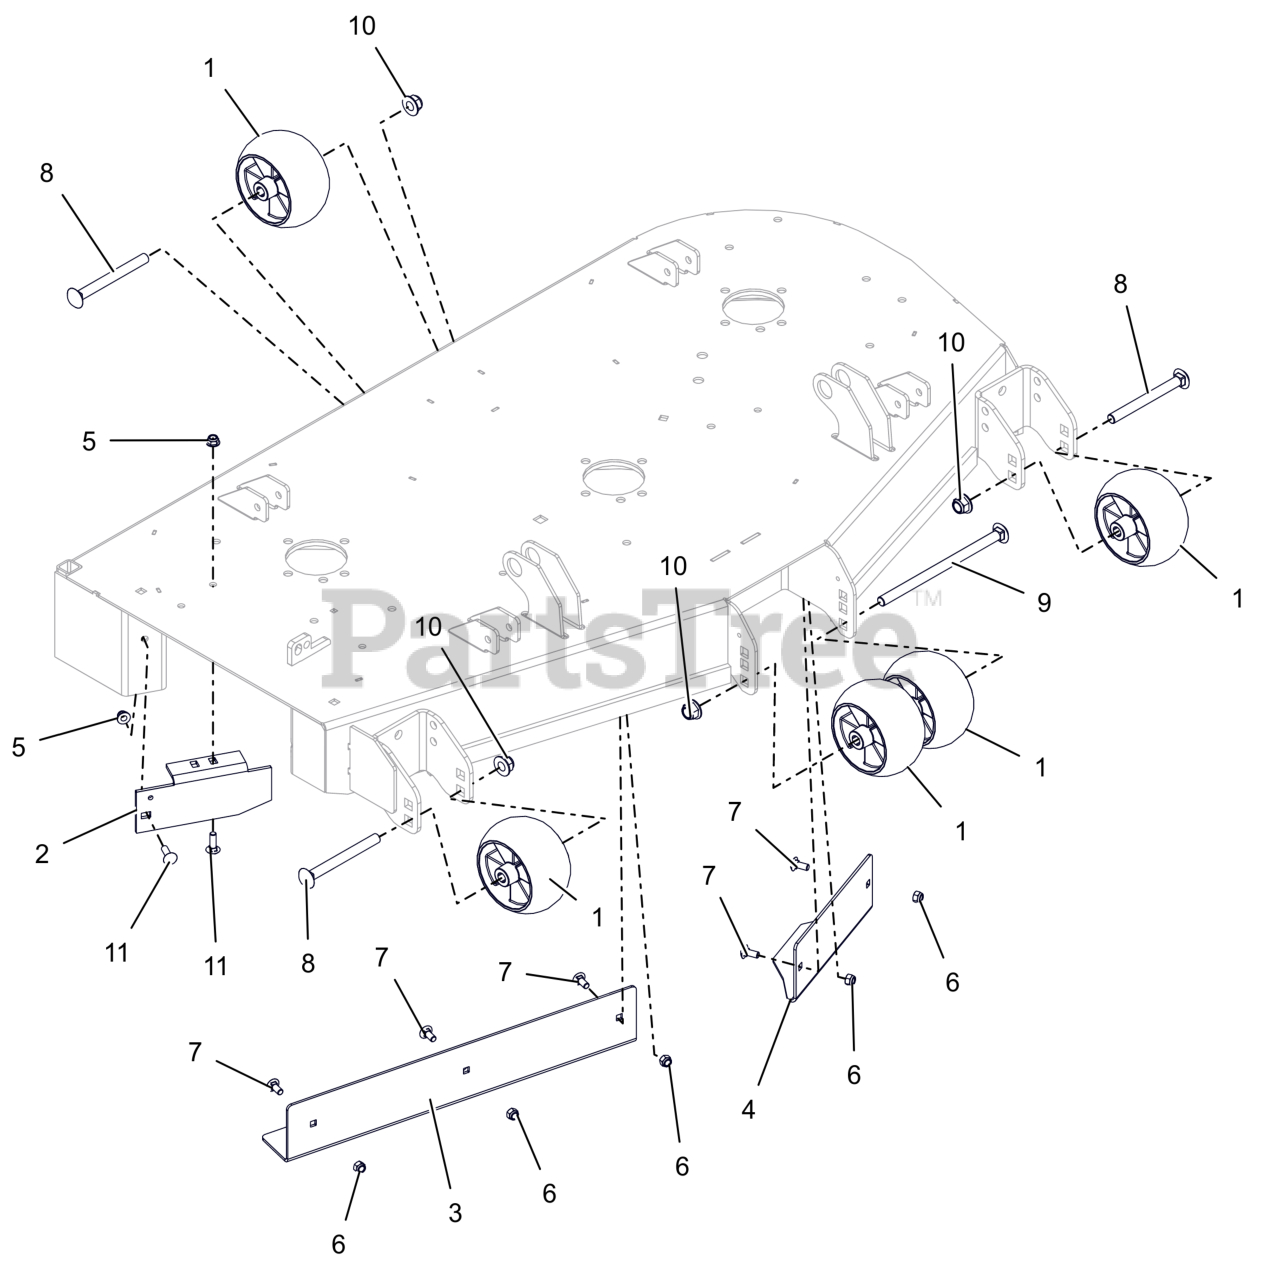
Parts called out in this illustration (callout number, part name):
1	WHEEL, ANTI SCALP - 5X3 CTR W/RIBS
2	44"-48" SIDE DISCH BAFFLE -RED
3	BAFFLE, 48" RH VACUUM (RED)
4	BAFFLE, 44/48" LH VACUUM (RED)
5	NUT,NYL-FLG .31-18 GF ZCC
6	NUT,NYL .31-18 G5 ZCC
7	BLT,RHSN .31-18X.75 G5 ZCC
8	BLT, RHSN .50-13X5.00 G5 ZCC
9	BTL,RHSN .500-13 X 8.5S G5 ZCC
10	NUT,NYL-FLG .50-13 GF ZCC
11	BLT,RHSN .31-18X1.00 G5 ZCC
